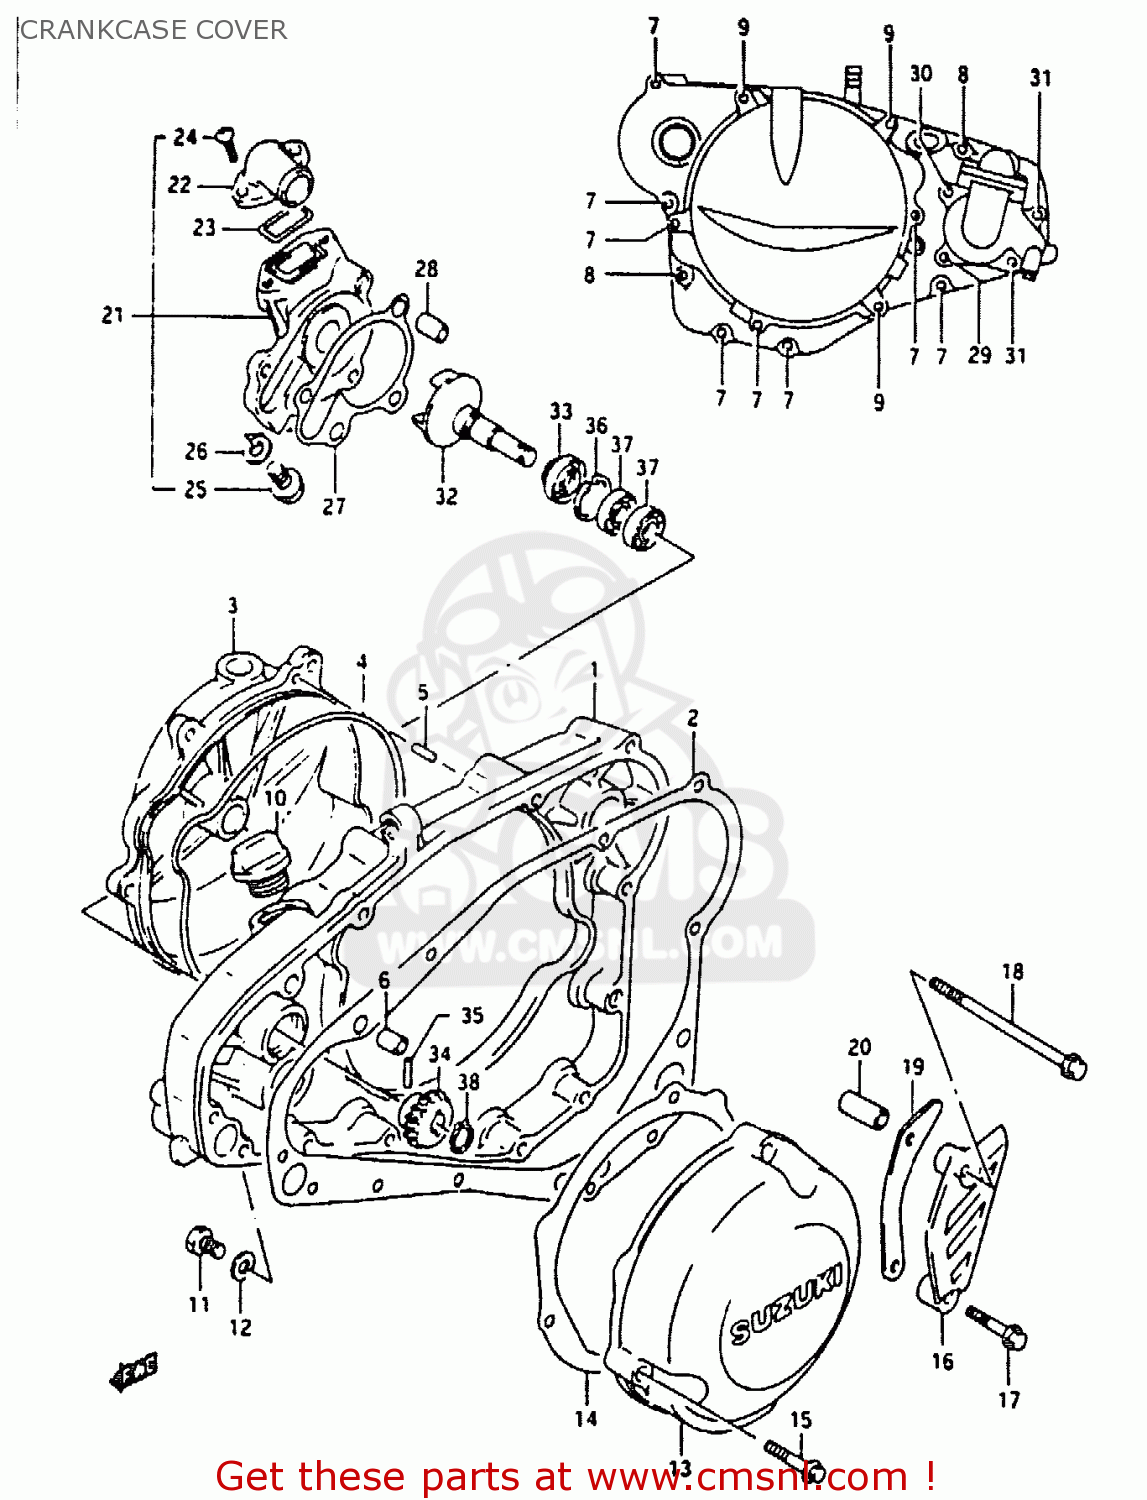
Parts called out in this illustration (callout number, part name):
1	COVER,CLUTCH
2	GASKET,CLUTCH COVER (NAS)
3	COVER,CLUTCH,OUTER
4	O RING,CLUTCH COVER OUTER
5	PIN
6	PIN
7	BOLT
8	BOLT
9	BOLT
10	PLUG SET
11	SCREW(6X10)
12	GASKET(6.2X11X1).2 (NAS)
13	COVER,MAGNETO
14	GASKET,MAGNETO COVER (NAS)
15	BOLT
16	COVER,SPROCKET
17	BOLT
18	BOLT
19	PLATE,FR CHAIN GUIDE(13T)
20	SPACER(6.5X10.5X25)
21	CASE,WATER PUMP
22	CONNECTOR
23	O RING,WATER PUMP CONNECTOR
24	SCREW
25	BOLT
26	WASHER
27	GASKET,WATER PUMP CASE (NAS)
28	PIN
29	BOLT
30	BOLT
31	BOLT
32	IMPELLER,WATER PUMP
33	SEAL,WATER PUMP OIL
34	GEAR,WATER PUMP DRIVEN
35	PIN(3X13.8)
36	CIRCLIP
37	BEARING
38	CIRCLIP,10MM
